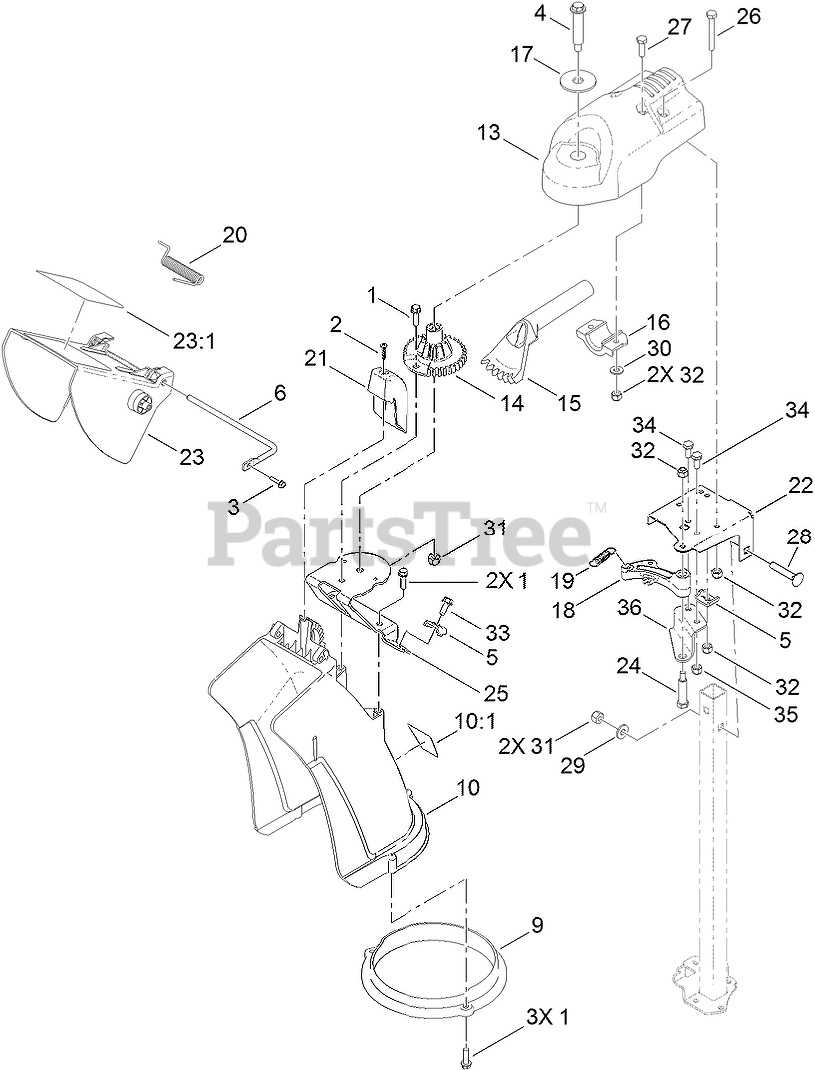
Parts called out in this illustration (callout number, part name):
1	SCREW-HWH
2	SCREW-PPH
3	SCREW-HWH
4	BOLT-SHOULDER
5	CLAMP-CABLE
6	ROD-DEFLECTOR
9	RING-CHUTE
10	CHUTE-DISCHARGE
10:1	DECAL-GUARANTEE
13	MOUNT-CHUTE, DISCHARGE
14	GEAR-CHUTE
15	GEAR-BEVEL
16	MOUNT-GEAR, BEVEL
17	WASHER-FLAT
18	LATCH-CHUTE
19	SPRING-LATCH, CHUTE
20	SPRING-TORSION
21	CHUTE-COVER
22	BRACKET-SUPPORT, CHUTE
23	DEFLECTOR-CHUTE
23:1	DECAL-DANGER
24	BOLT-SHOULDER
25	BRACKET-MOUNT, CHUTE
26	SCREW-HH
27	SCREW-HH
28	SCREW-CARR
29	WASHER-FLAT
30	WASHER-FLAT
31	NUT-LOCK, NI
32	NUT-LOCK, NI
33	SCREW-HWH
34	SCREW-HH
35	NUT-LOCK, NI
36	BRACKET-SUPPORT, LATCH
